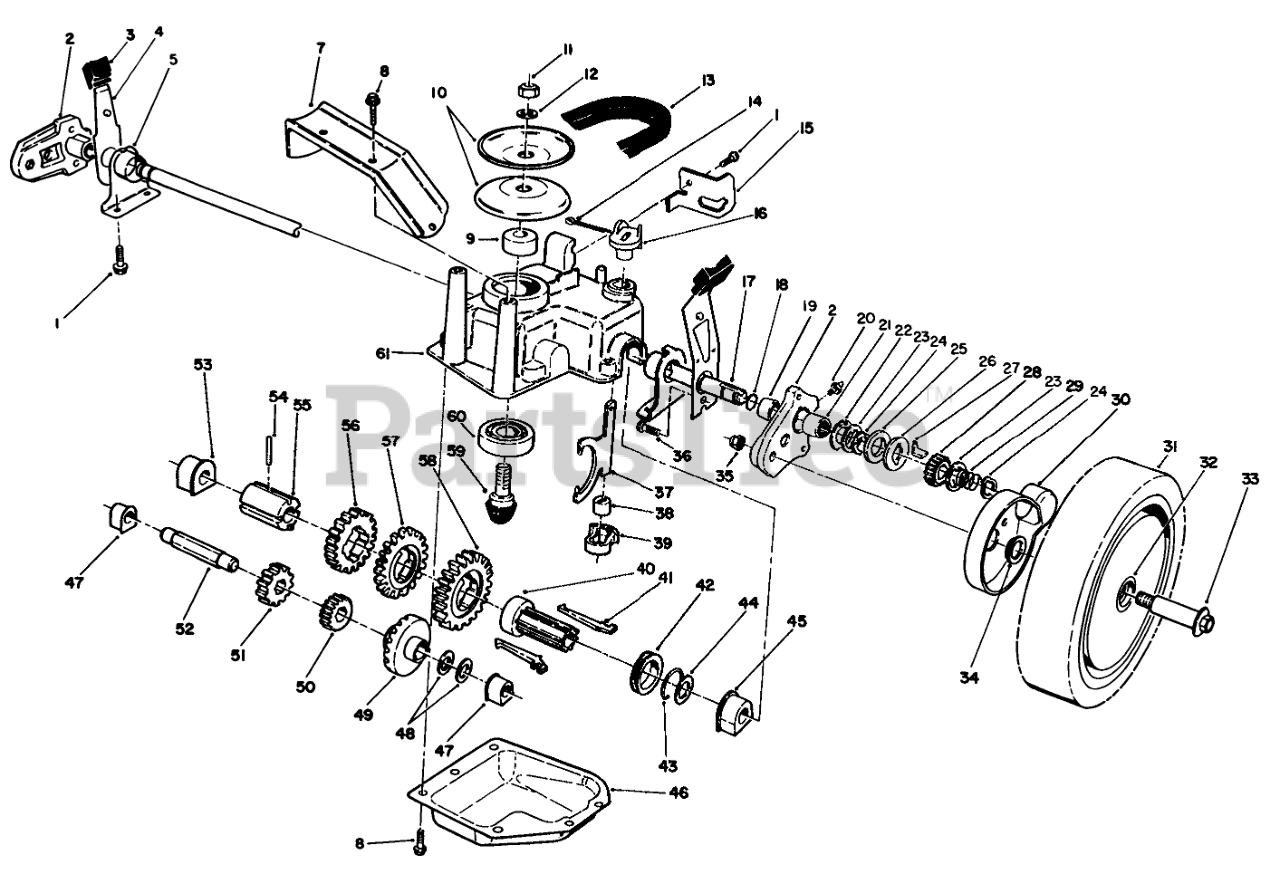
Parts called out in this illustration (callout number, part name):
1	SCREW-HWHTF
2	Pivot Arm Assembly (Incl. Ref. #19-21)
3	KNOB-ARM
4	SPRING ARM ASM
5	CAP-END
7	Bracket-BeltGuide
8	SCREW-HWHTF
9	SPACER
10	Pulley Half
11	NUT-HEX
12	WASHER-FLAT
13	V-BELT
14	PIN-COTTER
15	RETAINER-CABLE
16	LEVER-SHIFT
17	SHAFT-OUTPUT
18	O-RING
19	BUSHING
20	FITTING-GREASE
21	BEARING-ROLLER
22	WASHER-ARM, PIVOT
23	WASHER-THRUST, KEYED
24	RING-CLIP, LOCKING
25	RING-FRICTION
26	WASHER-CLUTCH
27	KEY-ROCKING, LH
28	GEAR-PINION
29	SPRING-COMPRESSION
30	COVER-WHEEL
31	Wheel Tire & Gear Assy. (Incl. Ref. #32)
32	BUSHING
33	WHEEL BOLT
34	SPACER-COVER, WHEEL
35	NUT-LOCK
36	SCREW-HSH, THREAD FORMING
37	YOKE-SHIFT
38	BUSHING-YOKE
39	RETAINER-FORK, SHIFT
40	SLEEVE-KEY, SHIFT
41	KEY-SHIFT
42	COLLAR-SHIFT
43	CLIP-SPRING
44	WASHER-PLAIN
45	BUSHING-OUTPUT
46	Cover-Gearcase
47	BUSHING
48	WASHER-THRUST
49	Gear-Bevel
50	PINION-20T
51	PINION-25T
52	SHAFT-INTERMEDIATE
53	BUSHING
54	PIN-SPRING
55	SLEEVE-GEAR
56	GEAR-39T
57	GEAR-44T
58	GEAR-49T
59	Gear-Pinion
60	BEARING-BALL
61	CASE-GEAR, UPPER
